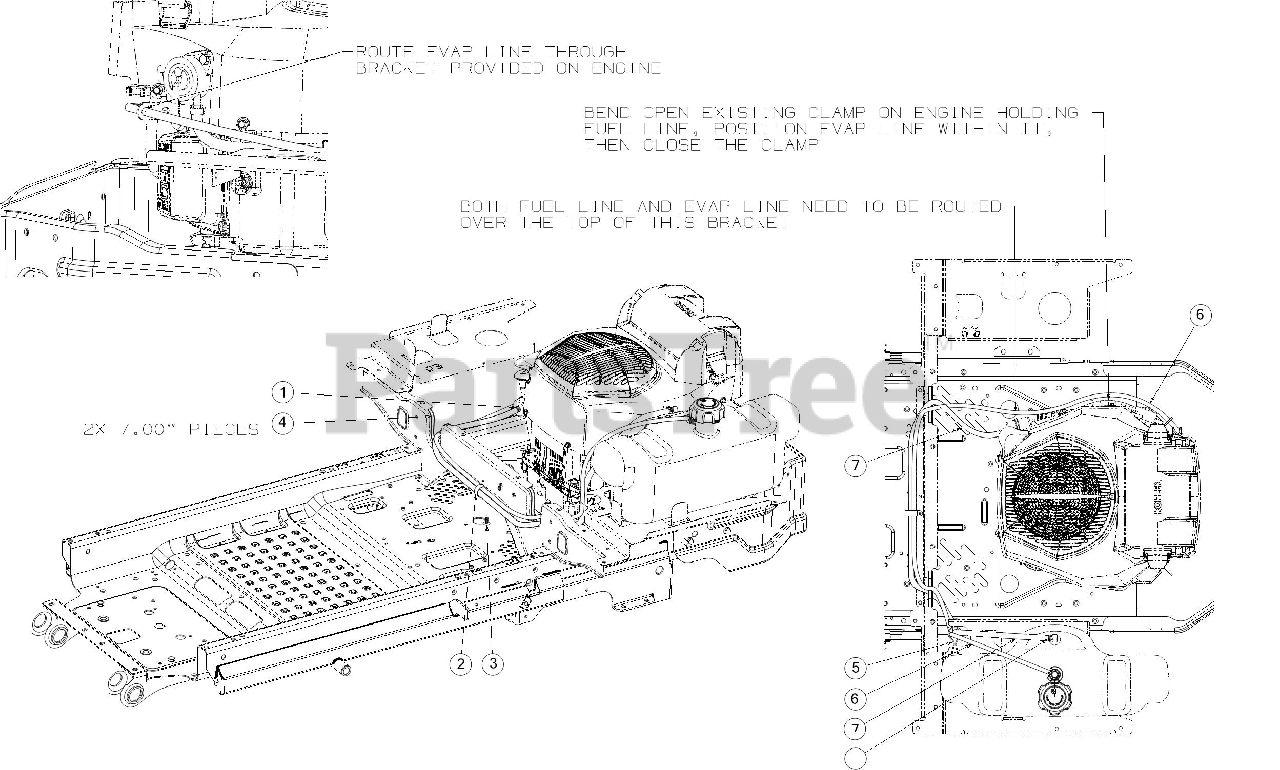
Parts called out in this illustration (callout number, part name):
1	HOSE CLAMP 1/20
2	DRAIN HOSE CLAMP
3	RATCHET CLIP .250
4	TRIM STRIP
5	TANK SUPPORT ROD
6	FUEL HOSE LOW PERMEATION
7	VENT HOSE 3/16 ID
